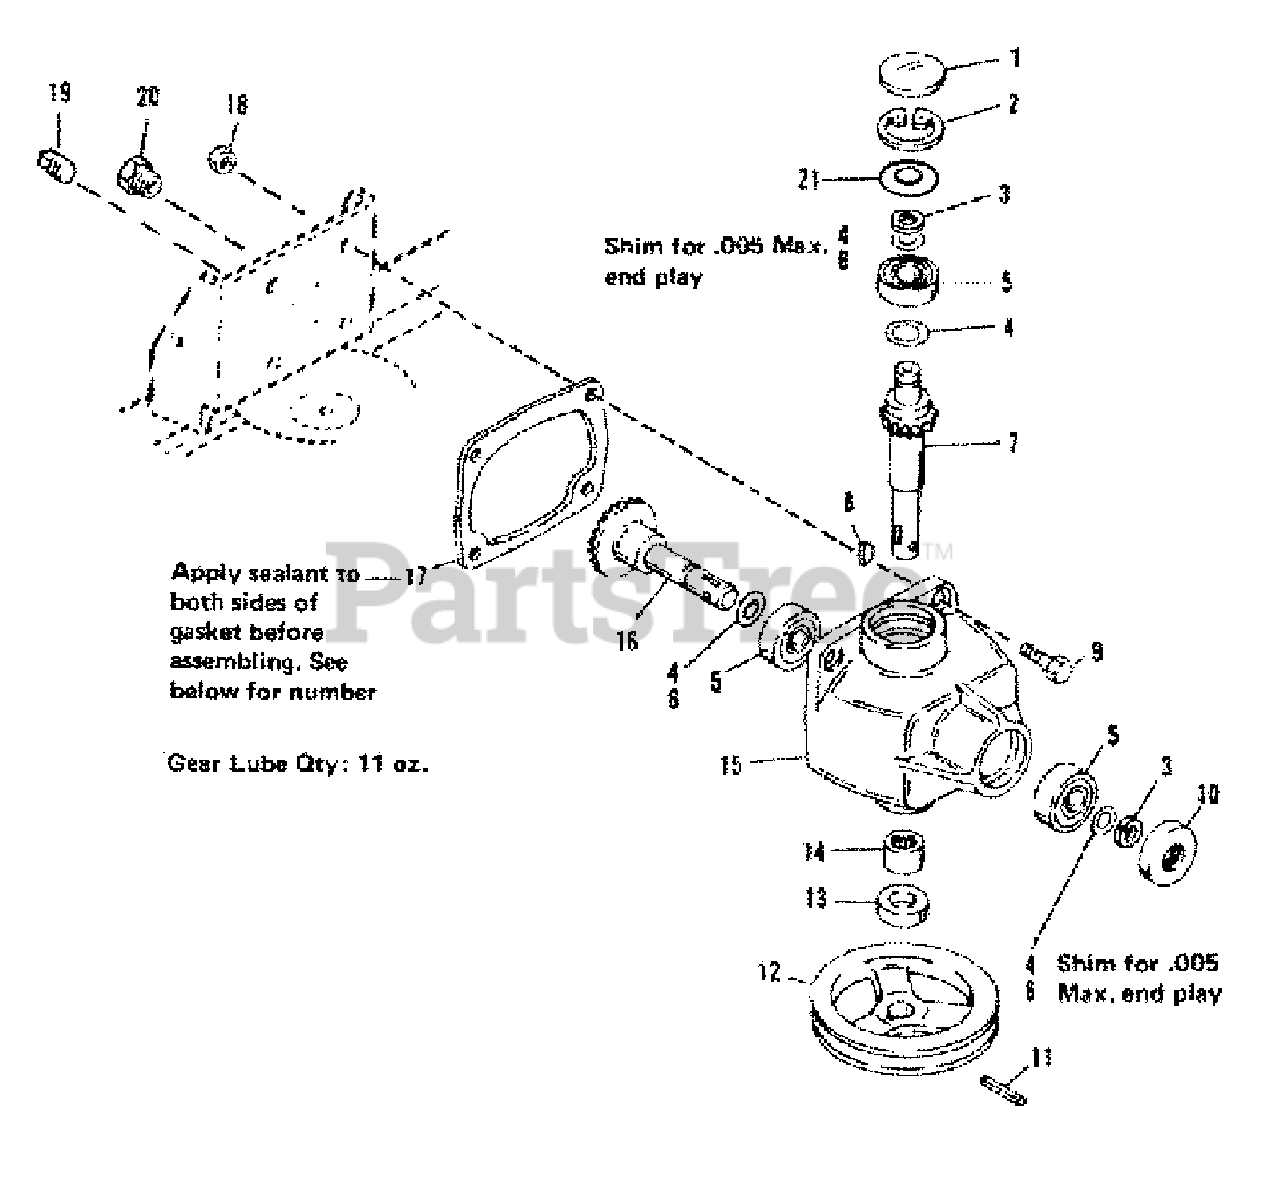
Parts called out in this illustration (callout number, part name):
1	Expansion Plug
2	Retaining Ring
3	Retaining Ring
4	Shim Washer .005
5	Ball Bearing
6	Shim .070
7	Output Shaft
8	Woodruff Key, 3/16 x 3/4
9	Hex Hd. Capscrew, 5/16-18 x 1-1/4
11	Drive Pin, 1/4 x 1-1/2
12	Drive Sheave
13	Oil Sea
14	Needle Bearing
15	Gear Case
16	Bevel Gear, 26T
17	Gear Case Gasket
18	Top Look Nut, 5/16-18
19	Square Plug, 3/8 NPT
20	Pressure Relief Valve
21	Shin .005
NI	Gear Lube, EP90 (8 oz.)
NI	Sealant 3 oz.
